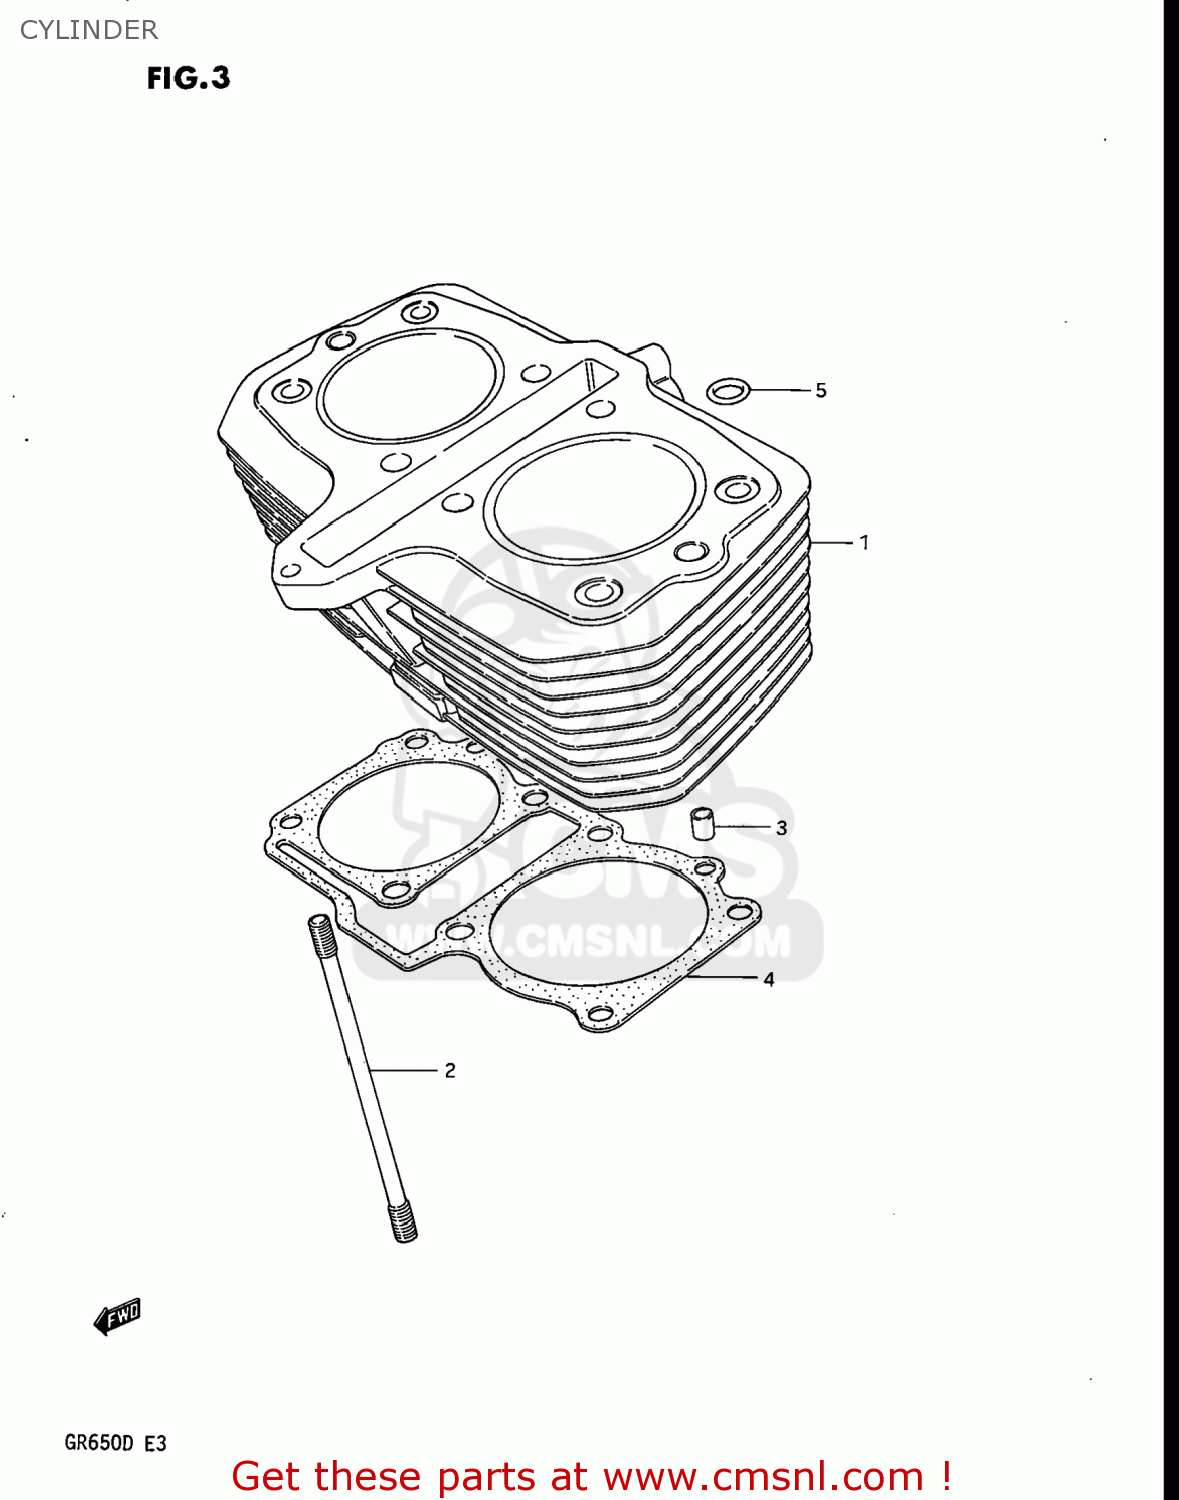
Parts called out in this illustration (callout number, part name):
1	CYLINDER
2	STUD
3	PIN
4	GASKET,CYLINDER
5	O RING(D:2.4,ID:11)
